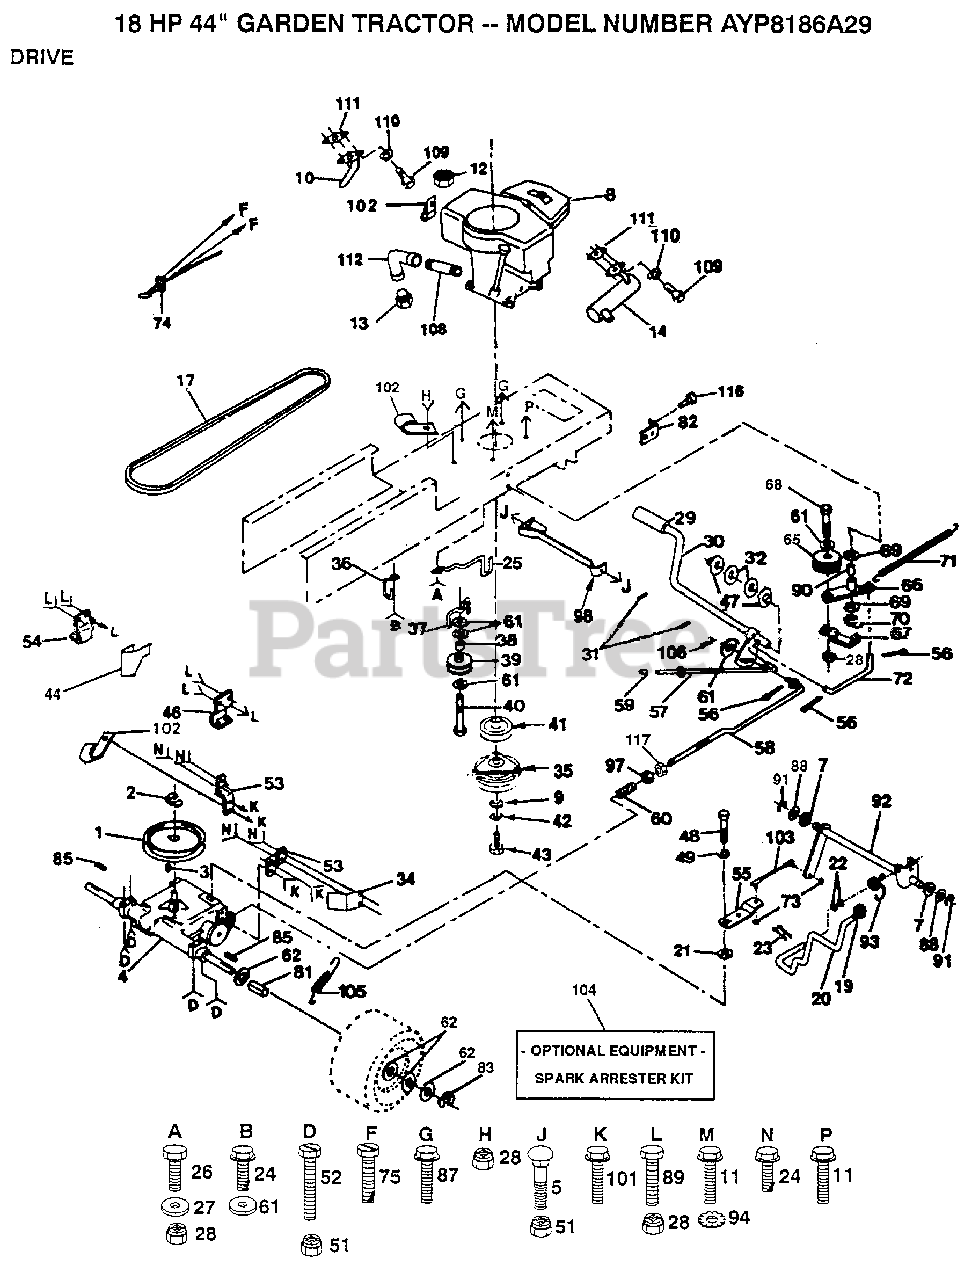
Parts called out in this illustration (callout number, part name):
1	PULLEY TRANSAXLE
2	RING
4	TRANSAXLE PEERLESS MODEL NO
5	BOLT
7	BUSHING
9	WASHER
10	EXHAUST TUBE T
11	SCREW LT
12	NUT
17	BELT.GRDRV.94.75
19	KNOB T (1/2-HOLE)
21	WASH-SHFT PLT LT
22	WASHER
23	PIN COTTER 1/8
24	SCREW
25	KEEPER.BELT.ENG.L
26	BOLT
27	WASHER
29	PEDAL COVER T
32	WASHER LT
34	"KEEPER,BELT RH"
36	RETAINER BELT
37	BELT KEEPER LT
38	SPACER T
39	PULLEY.IDLER.FLAT
40	BOLT
42	LOCKWASHER
44	KEEPER BELT LH
46	BRKT TRANS RH
47	NYLON BEARING
49	WASHER PM
52	BOLT
53	STRAP TORQUE
54	BRKT TRANS LH
55	"ARM,SHIFT"
56	COTTER PIN
57	BRAKE PARK ROD
58	ROD BRAKE
59	PLUNGER CAP T
60	"SPRING,ROD BRAKE"
61	WASHER
62	WASHER
66	ARM IDLER
67	RETAIN BELT
69	WASHER LT
70	KLIP RING
71	"SPRING, RETURN LT"
72	"LINK, CLUTCH T"
73	NUT 1/4-28
75	SCREW LT
81	SPACER HYT
82	BRACKET LT
83	E RING HYT
85	SQ KEY STD
87	SCREW LT
88	WASHER D
90	"LY, BEARING"
91	KLIP RING
92	"SHAFT,SHIFTER"
93	"SPRING,TORSION"
94	LOCKWASHER
97	NUT
101	SCREW
102	CLIP T
103	"ROD,TIE "
106	RETAINER M
108	PIPE NIPPLE LT
110	LOCKWASHER
112	ELBOW
116	SCREW
117	NUT
